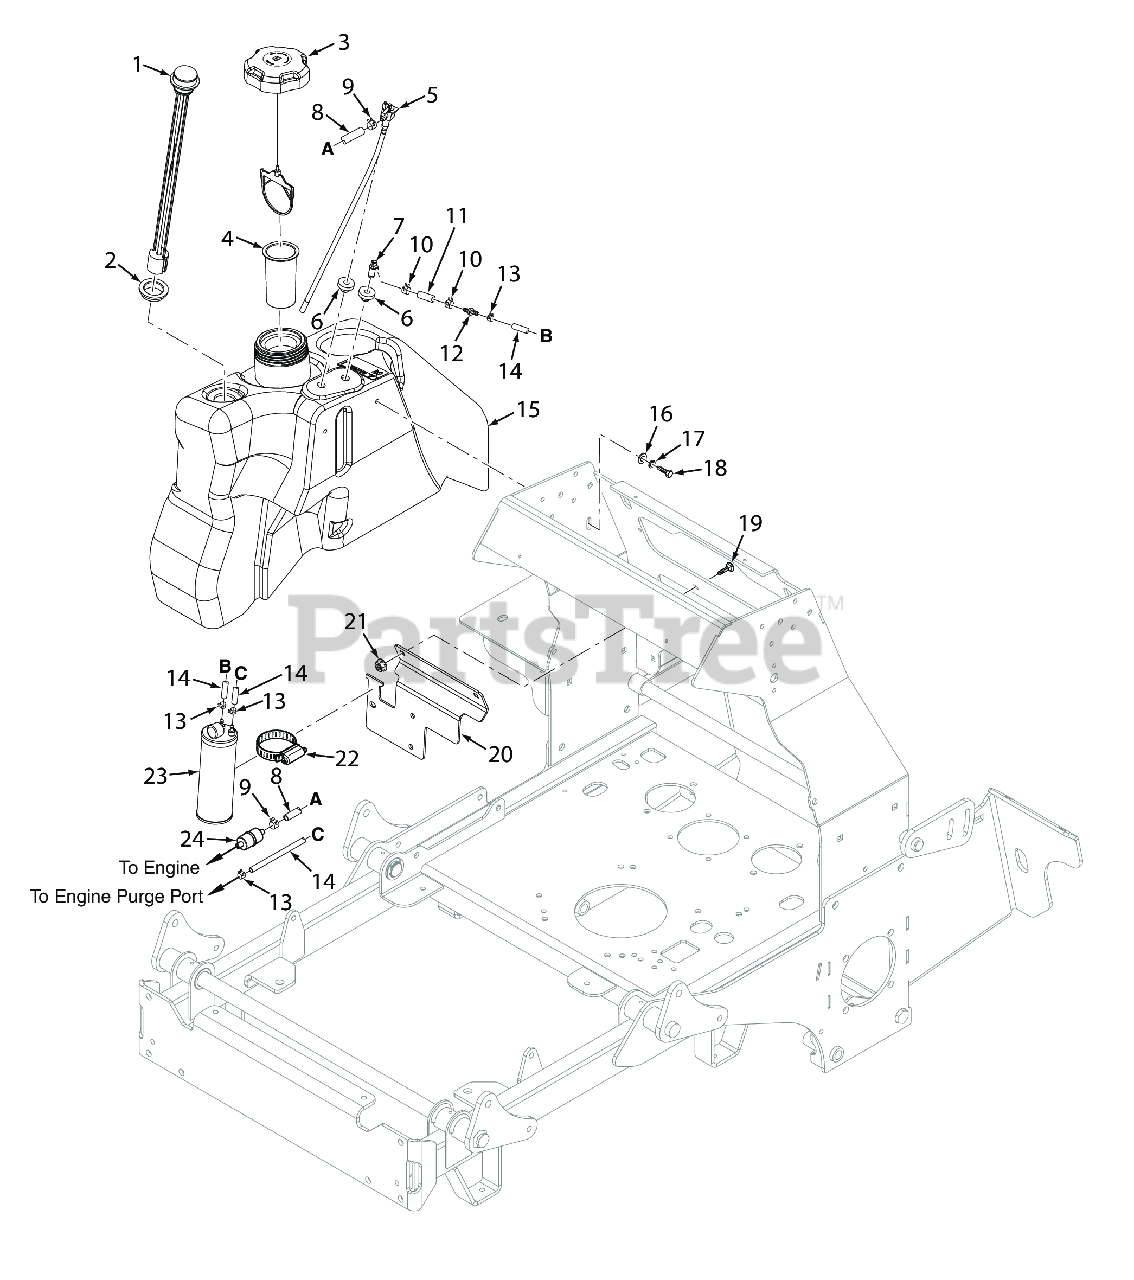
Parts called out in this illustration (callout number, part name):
1	Fuel Gauge Assy., 15-1/2" (36)
1	Fuel Gauge Assy., 16-1/2"
2	Grommet, Fuel Gauge
3	Fuel Cap w/ Tether (E.P.A.)
3	Fuel Cap, Tethered - CA models only
4	Tube, Fuel Tank Insert
5	Valve, Fuel Shutoff (36)
5	Valve, Fuel Shut Off
6	Bushing, 0.56" Dia. Viton
7	Remote Vent
8	Fuel Hose, 1/4" I.D. Non-Perm (791DFI Fuel Return) - Order by Inch
9	Clamp, Fuel Hose 1/4" Hose I.D.
10	CLAMP, FUEL HOSE(KAWASAKI ONLY)
11	Hose, 1/4" Vapor Recovery (order by inch)
12	Mender, 1/4 x 3/16 w/0.02 Hole
13	Clamp, Vapor Recovery Hose 3/16"
14	Hose, Vapor Recovery 3/16" (order by inch)
15	Fuel Tank Assy., SVRII-36 (Incl. #1,2,5,6,7)
15	Fuel Tank Assy., SVRII (Incl. #1,2,5,6,7)
16	Flatwasher, 5/16-.375 x .875 x .083 (35BV & 37BV-EFI)
17	Lockwasher, 5/16 (.317 x .586 x .078) Helical Spring
18	BOLT, SERRATED FLANGE HEX HEAD 5/16-18 X 3/4"
19	Bolt, 5/16-18 x .75 RHSN Carriage
20	Bracket, Hydro Tank Mounting
21	Nut, Serrated Flange 5/16-18 (Right Front Engine Mounting, Briggs and Kohler Only)
22	Clamp, 3-1/2" Max. Dia.
23	Carbon Canister - SVR-52V / SVR-61V
24	Fuel Filter
